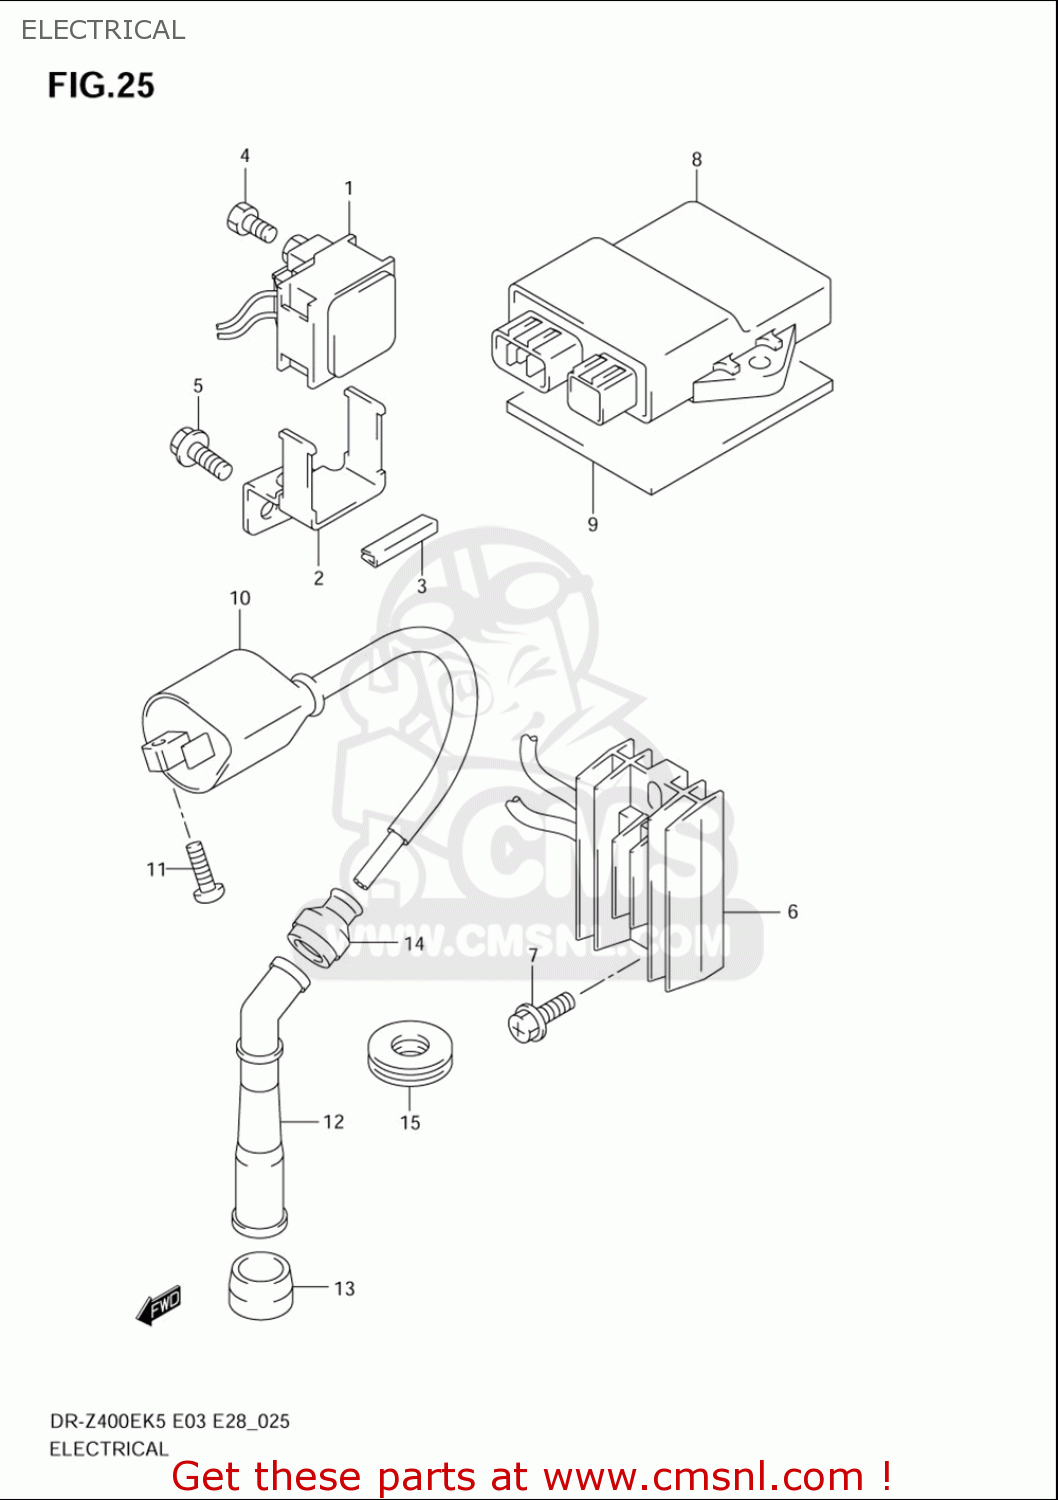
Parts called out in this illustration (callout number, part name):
1	RELAY ASSY,STARTING MOTOR
2	BRACKET,STARTING MOTOR RELAY
3	PROTECTOR,STARTING MOTOR LEAD
4	SCREW(6X8)
5	BOLT
6	RECTIFIER ASSY
7	BOLT
8	CDI UNIT
9	PROTECTOR(170X95X3.0)
10	COIL ASSY,IGNITION
11	BOLT
12	CAP,SPARK PLUG
13	SEAL,SPARK PLUG CAP
14	SEAL,HIGH TENSION CORD
15	COVER,SPARK PLUG CAP
